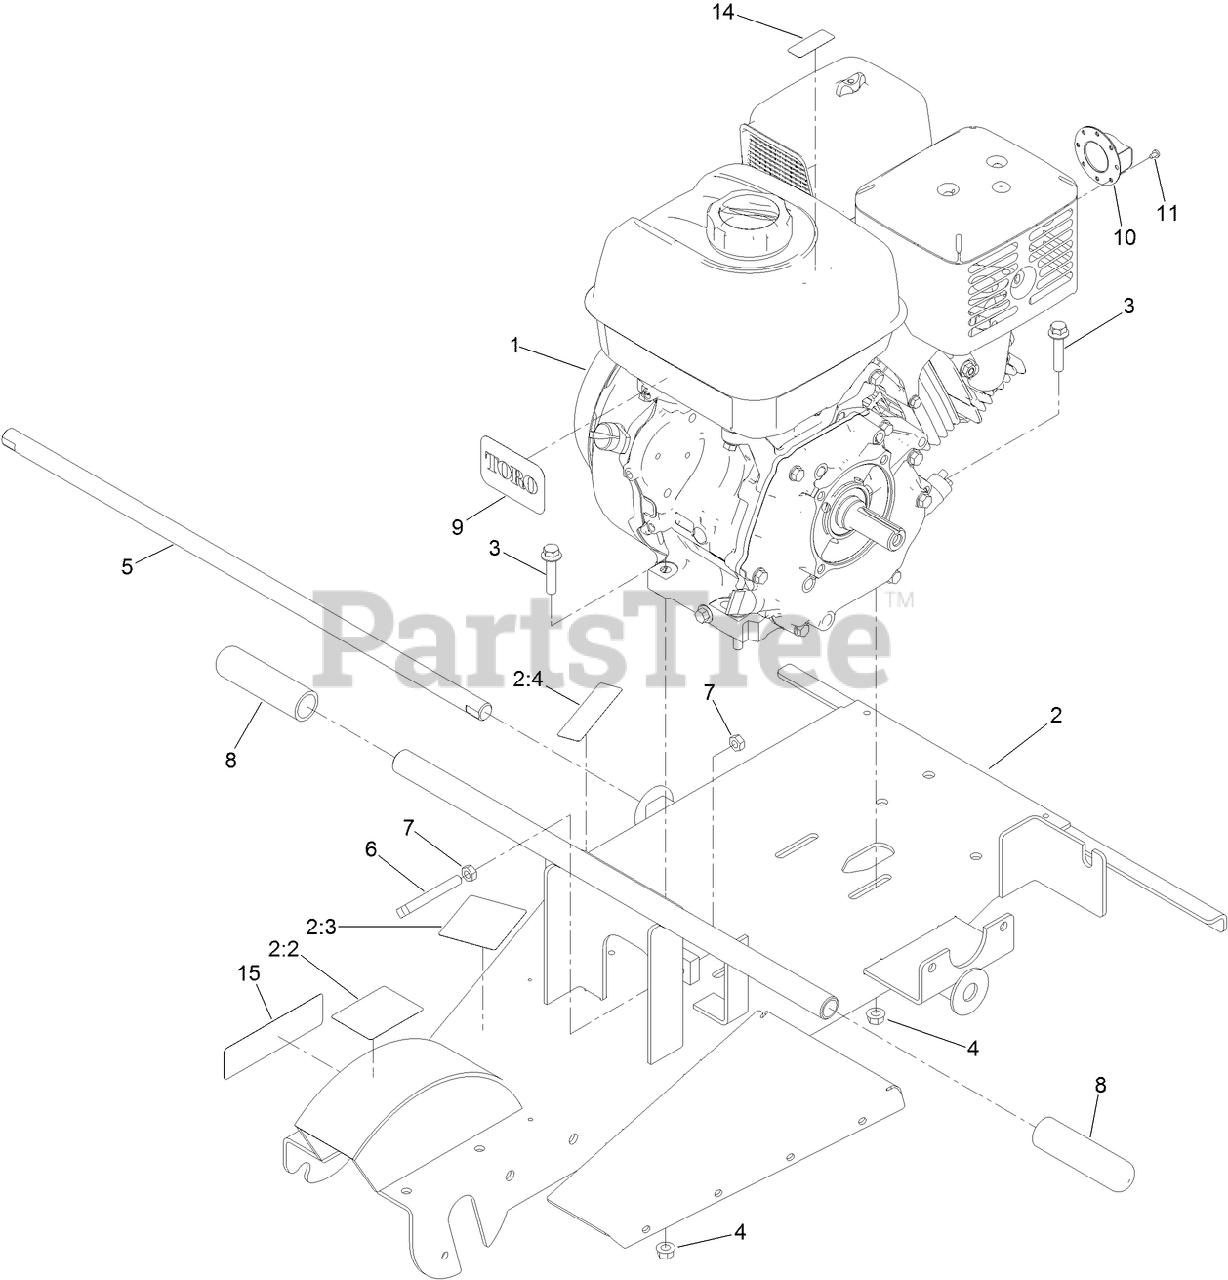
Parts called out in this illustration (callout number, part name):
2	FRAME ASM
2:2	DECAL-DANGER
2:3	DECAL-CAUTION
2:4	DECAL-ARRESTER, SPARK
3	SCREW-HHF
4	NUT-HF
5	BAR-AXLE
6	SCREW-SET, SQH
7	NUT-HEX
8	GRIP-HANDLE
9	DECAL
10	DEFLECTOR-EXHAUST, HONDA
11	SCREW-SELF TAPPING
14	DECAL-WARNING, ETHANOL
15	DECAL-ROTATE TOOTH
